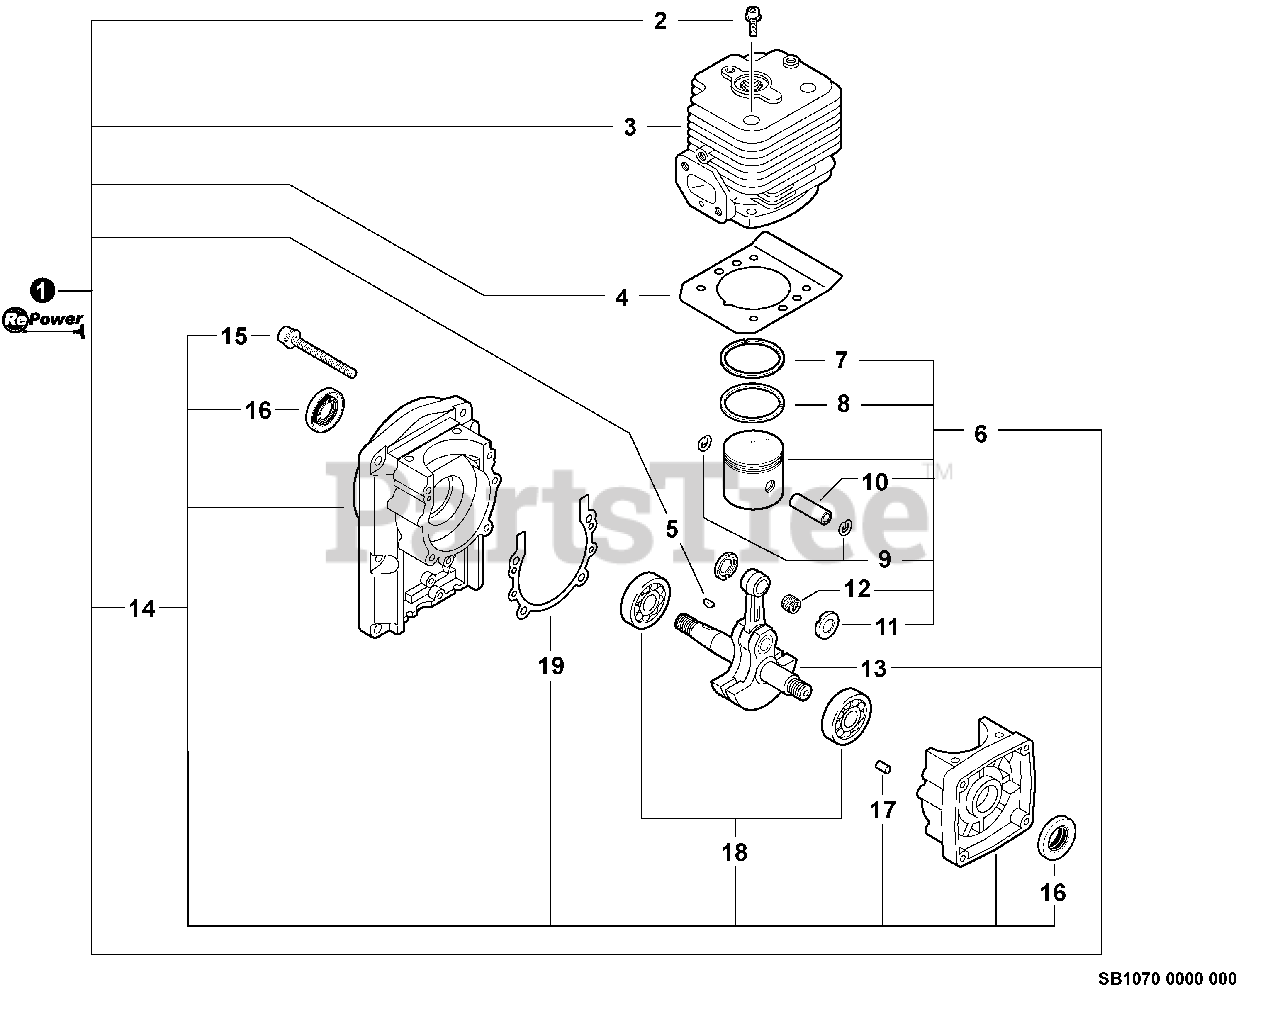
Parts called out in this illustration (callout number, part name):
1	SHORT BLOCK
2	BOLT 5×25
3	CYLINDER
4	GASKET, CYLINDER
5	KEY, WOODRUFF 3×14
6	PISTON KIT
7	RING, PISTON
8	RING, PISTON
9	RING, SNAP 8
10	PIN, PISTON
11	WASHER, THRUST
12	BEARING, NEEDLE 10
13	CRANKSHAFT ASSY
14	CRANKCASE KIT
15	BOLT M5×35
16	SEAL, OIL 15
17	PIN, LOCATING 4×8
18	BEARING, BALL 6302
19	GASKET, CRANKCASE
